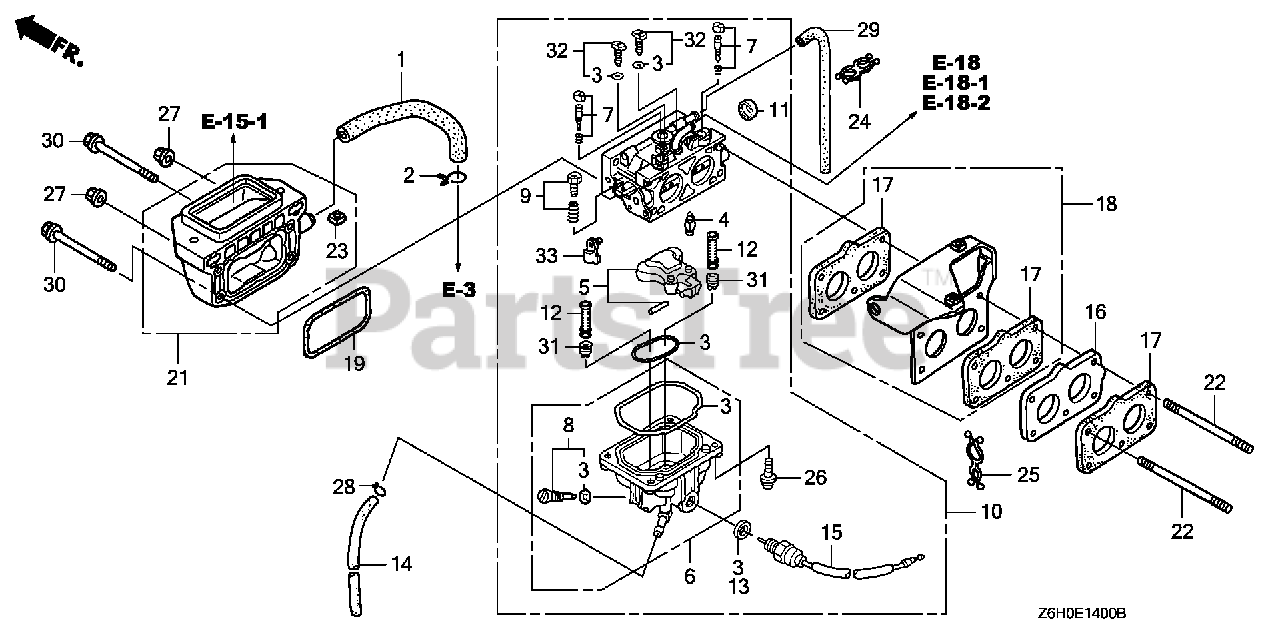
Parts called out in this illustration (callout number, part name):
3	GASKET SET
4	VALVE SET, FLOAT
6	CHAMBER SET, FLOAT
7	SCREW SET, PILOT
8	SCREW SET, DRAIN
9	SCREW SET, THROTTLE
10	CARBURETOR ASSY. (BK02A A)
11	CAP, CHOKE DUST
12	NOZZLE, MAIN (CARBURETOR NO.)
13	WASHER, PLAIN
14	TUBE, DRAIN
15	VALVE ASSY., SOLENOID (KEIHIN)
16	INSULATOR, CARBURETOR
17	GASKET, CARBURETOR
22	BOLT, STUD (6X108)
24	CLIP, WIRE HARNESS
25	CLIP, PURSE LOCK
26	SCREW, PAN (4X12)
28	CLIP, TUBE (B8)
29	BULK HOSE, VACUUM (4.5X1000) (4.5X540)
30	BOLT, FLANGE (6X95)
31	JET, MAIN (#92) (CARBURETOR NO.)
31	JET, MAIN (#98) (CARBURETOR NO.)
31	JET, MAIN (#102)
32	JET SET, PILOT (#40) (CARBURETOR NO.)
33	ARM, THROTTLE LINKAGE
